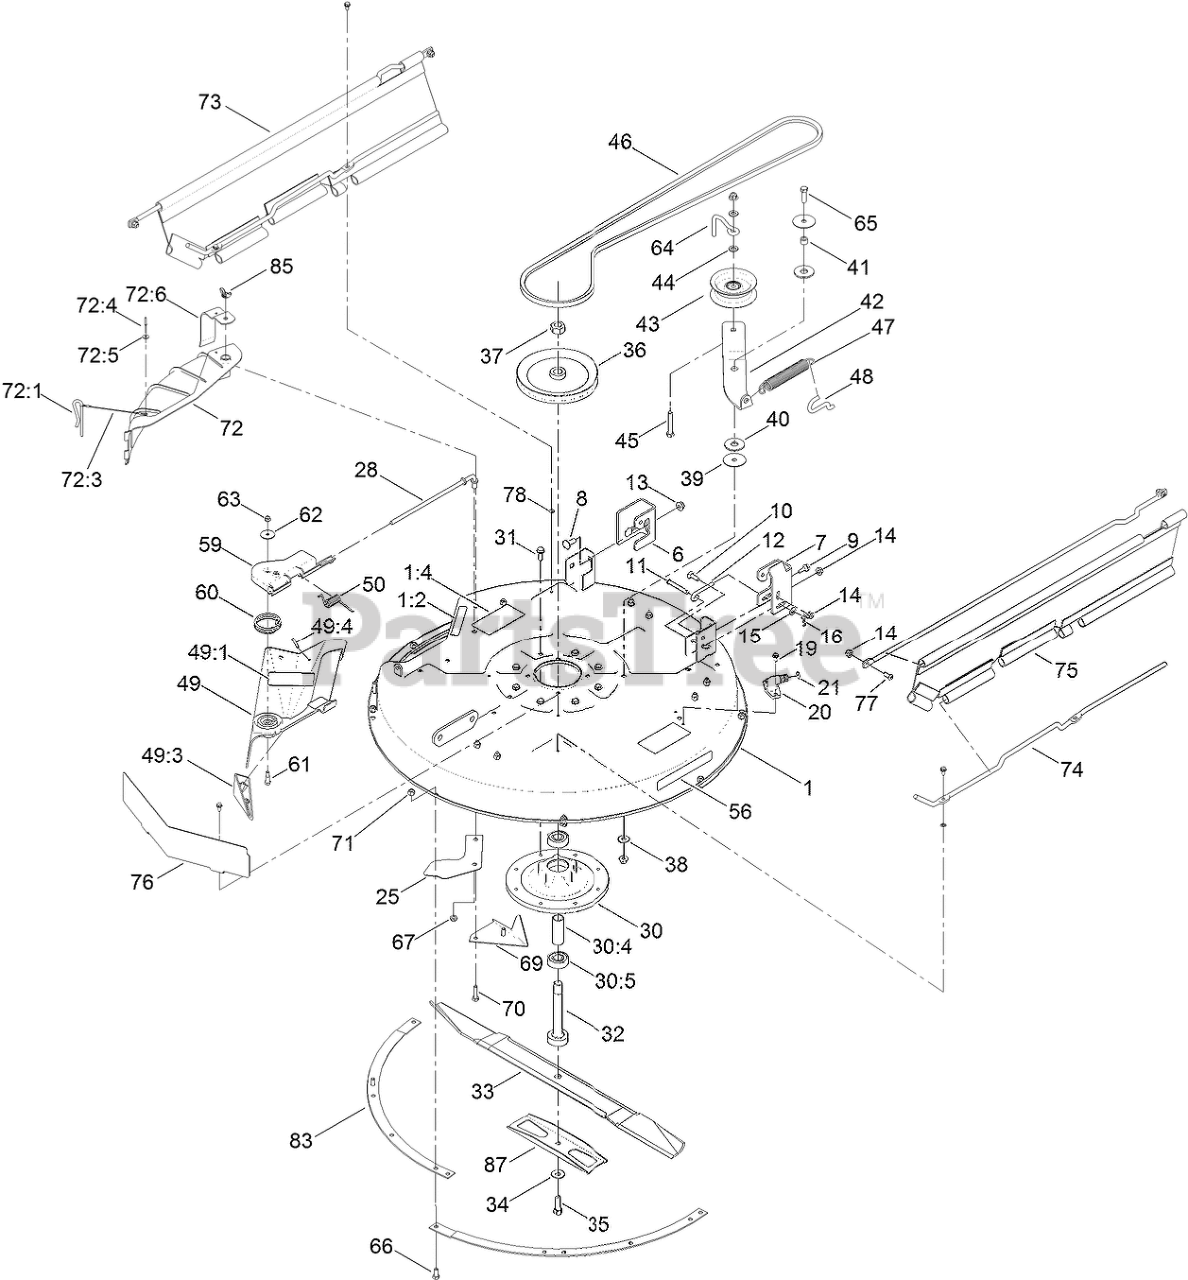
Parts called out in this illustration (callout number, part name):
1	32 INCH DECK AND DECAL ASM
1:2	DECAL-DANGER
1:4	DECAL-DANGER, DECK
6	BRACKET-HANGER, RH
7	BRACKET-HANGER, LH
8	BOLT-CARR
9	SCREW-SHOULDER, HHF
10	SCREW-CARR
11	PIN-CLEVIS
12	ROD-LEVEL, DECK
13	NUT-HF, NI
14	NUT-HF, NI
15	WASHER-PLAIN
16	PIN-COTTER
19	SCREW-HWH
20	FITTING-WASHOUT
21	O-RING
25	RAMP-DEFLECTOR
28	ROD-PIVOT
30	SPINDLE HOUSING ASM
30:4	BEARING-BALL
30:5	SPACER-BEARING
31	SCREW-TAPTITE
32	SHAFT-SPINDLE
33	BLADE-RECYCLER, 31.35 INCH
34	WASHER-BELLEVILLE
35	SCREW-HH
36	PULLEY-DECK
37	NUT-HEX
38	WASHER-HARDENED
39	WASHER
40	WASHER-FRICTION, COMPOSITE
41	SPACER
42	ARM-IDLER
43	PULLEY-IDLER, FLAT
44	WASHER-FLAT
45	SCREW-HH
46	V-BELT, 81.8 INCH
47	SPRING-EXTENSION
48	HOOK-RETURN, SPRING
49	32 INCH DEFLECTOR ASM
49:1	DECAL-DANGER
49:3	KICKER
49:4	SCREW-PPH
50	SPRING-TORSION
56	DECAL-RECYCLER
59	PIVOT-HINGE, DEFLECTOR
60	SPRING-TORSION
61	BOLT-SHOULDER
62	WASHER-FLAT
63	NUT-LOCK, NI
64	GUIDE-IDLER, BELT
65	SCREW-HH
66	SCREW-HH
67	NUT-LOCK, NI
70	SCREW-HH
71	NUT-LOCK, NI
72	DISCHARGE COVER ASM
72:1	PIN-LOCKING, CHUTE
72:3	LANYARD
72:4	RIVET-BLIND
72:5	WASHER-PLAIN
73	ROD-SUPPORT, UPPER
74	ROD-SUPPORT, LOWER
75	GUARD-SIDE
76	SHIELD-FRONT
77	SCREW-HSBH
78	NUT-RETAINING
83	RING-DECK
85	NUT-WING
87	STIFFENER
